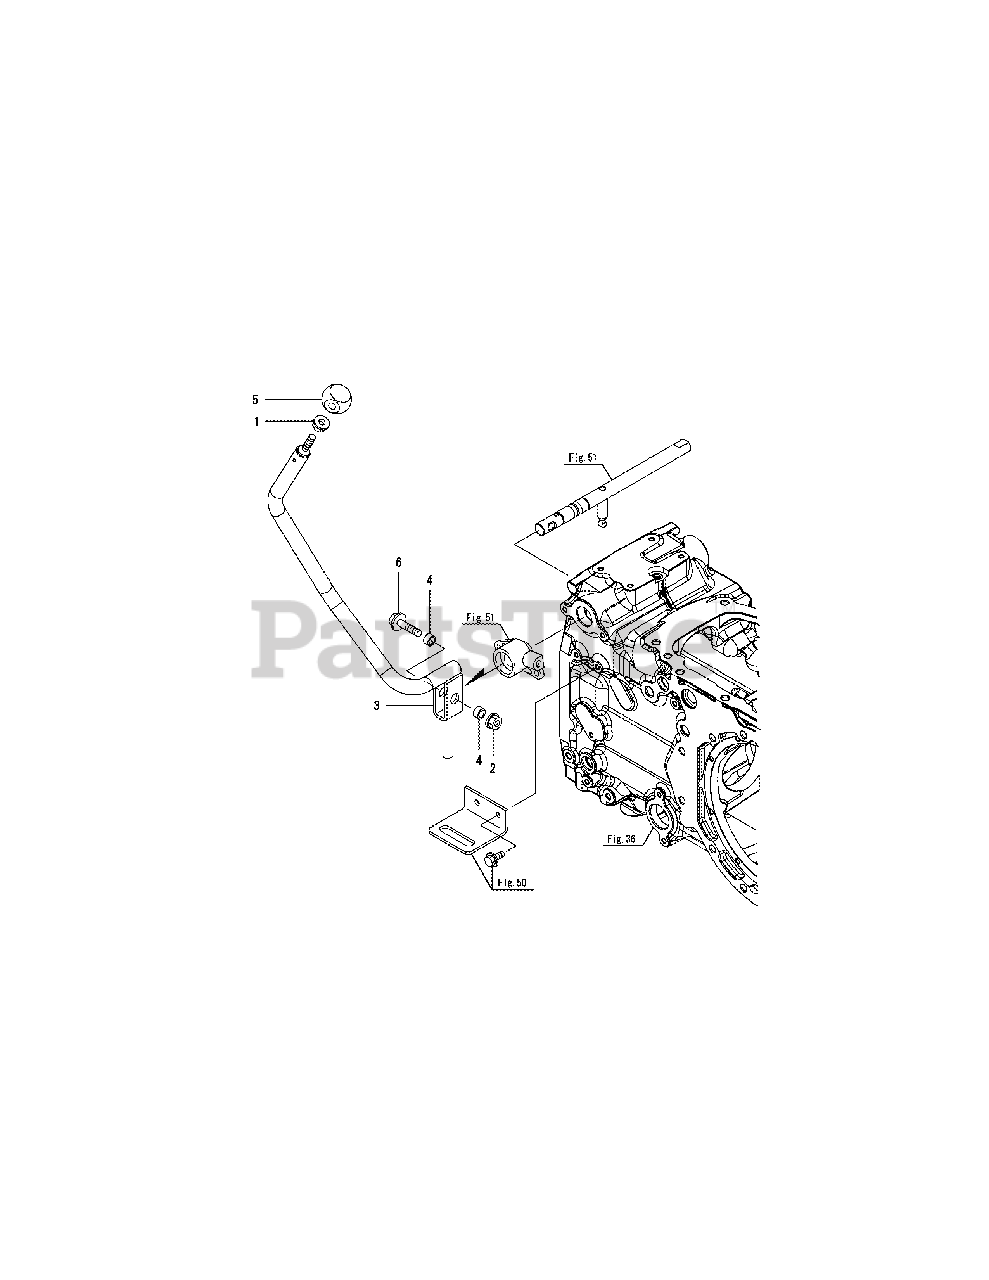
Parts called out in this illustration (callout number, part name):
1	NUT W/WASHER 10
2	NUT W/WASHER 10
3	LEVER, MAIN SHIFT
4	COLLAR, 11X16X8.5
6	BOLT M10X 40 PLATED
